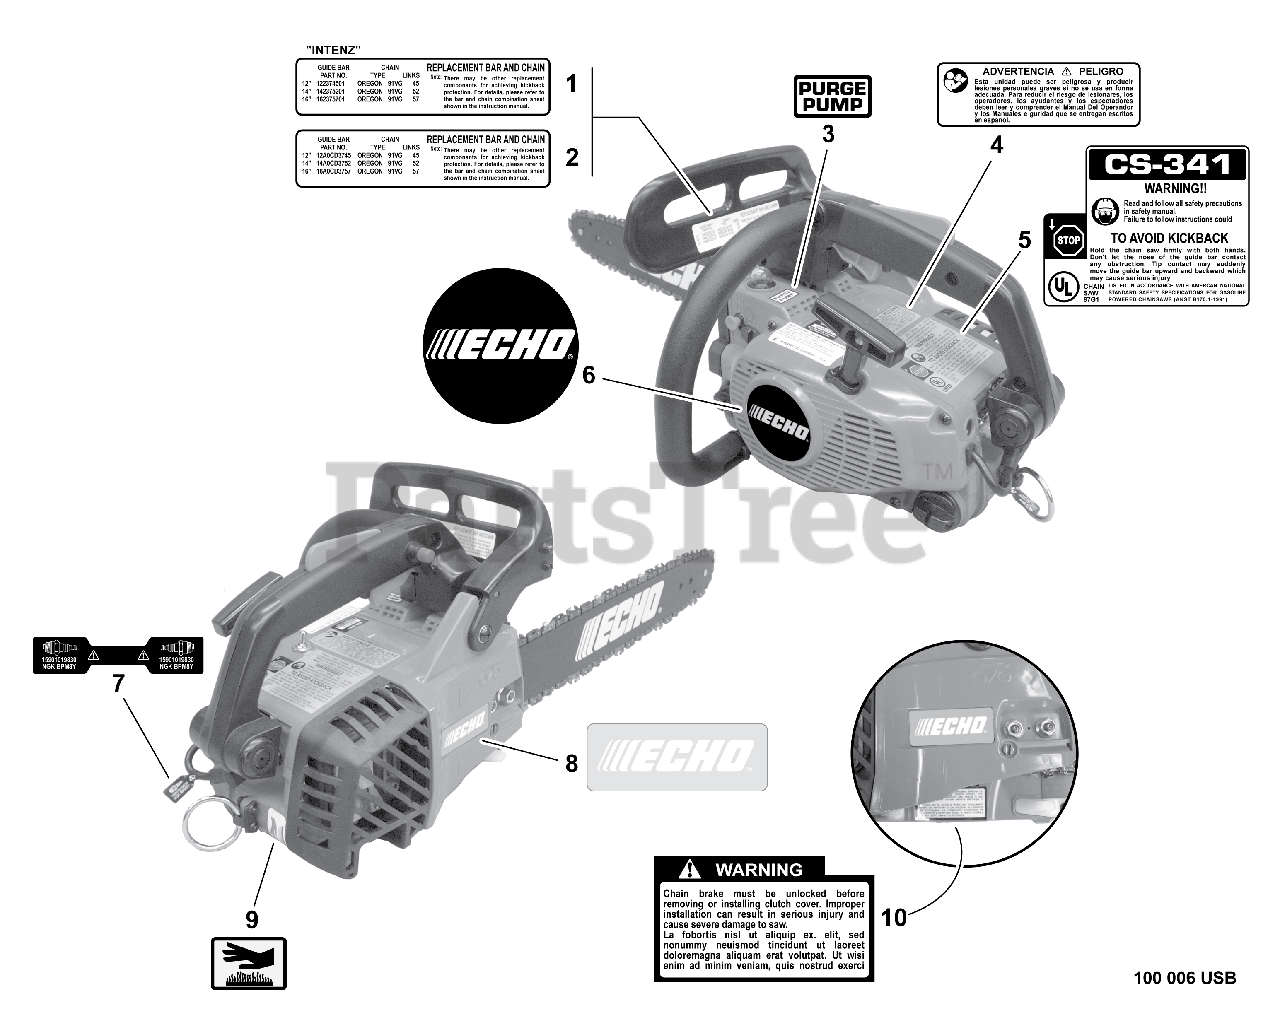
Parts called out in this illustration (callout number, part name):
1	LABEL - BAR & CHAIN -- US
2	LABEL - BAR & CHAIN
3	LABEL - PURGE PUMP
4	LABEL - CAUTION -- SPANISH
5	LABEL - KICK BACK
6	LABEL - ECHO
7	LABEL - SPARK PLUG -- BPM-8Y
8	LABEL - ECHO
9	LABEL - HOT SURFACE
10	LABEL - CAUTION
